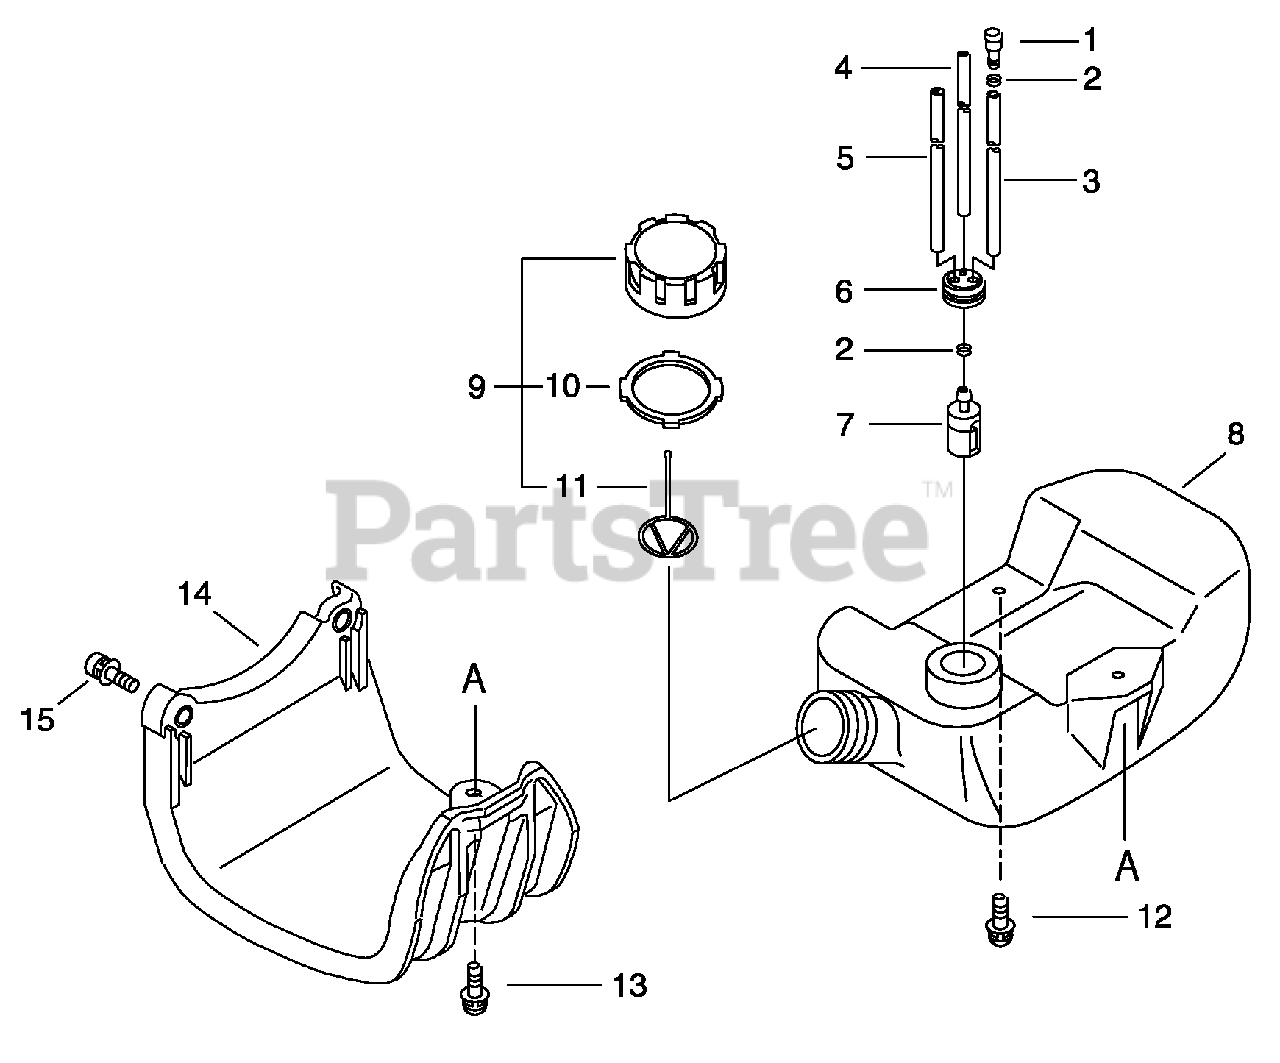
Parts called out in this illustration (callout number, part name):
1	VENT ASSY
2	CLIP Ø6.5 MM
3	PIPE, FUEL 3×6×100
4	PIPE, FUEL 3×6×170
5	PIPE, FUEL 3×6×60 CLEAR
6	GROMMET, FUEL
7	FILTER, FUEL
8	TANK, FUEL
9	CAP ASSY, FUEL
10	GASKET, FUEL CAP
11	CONNECTOR, CAP L= 100 MM
12	SCREW 5×16
13	SCREW 5×20
14	GUARD, FUEL TANK
15	BOLT 5×22
